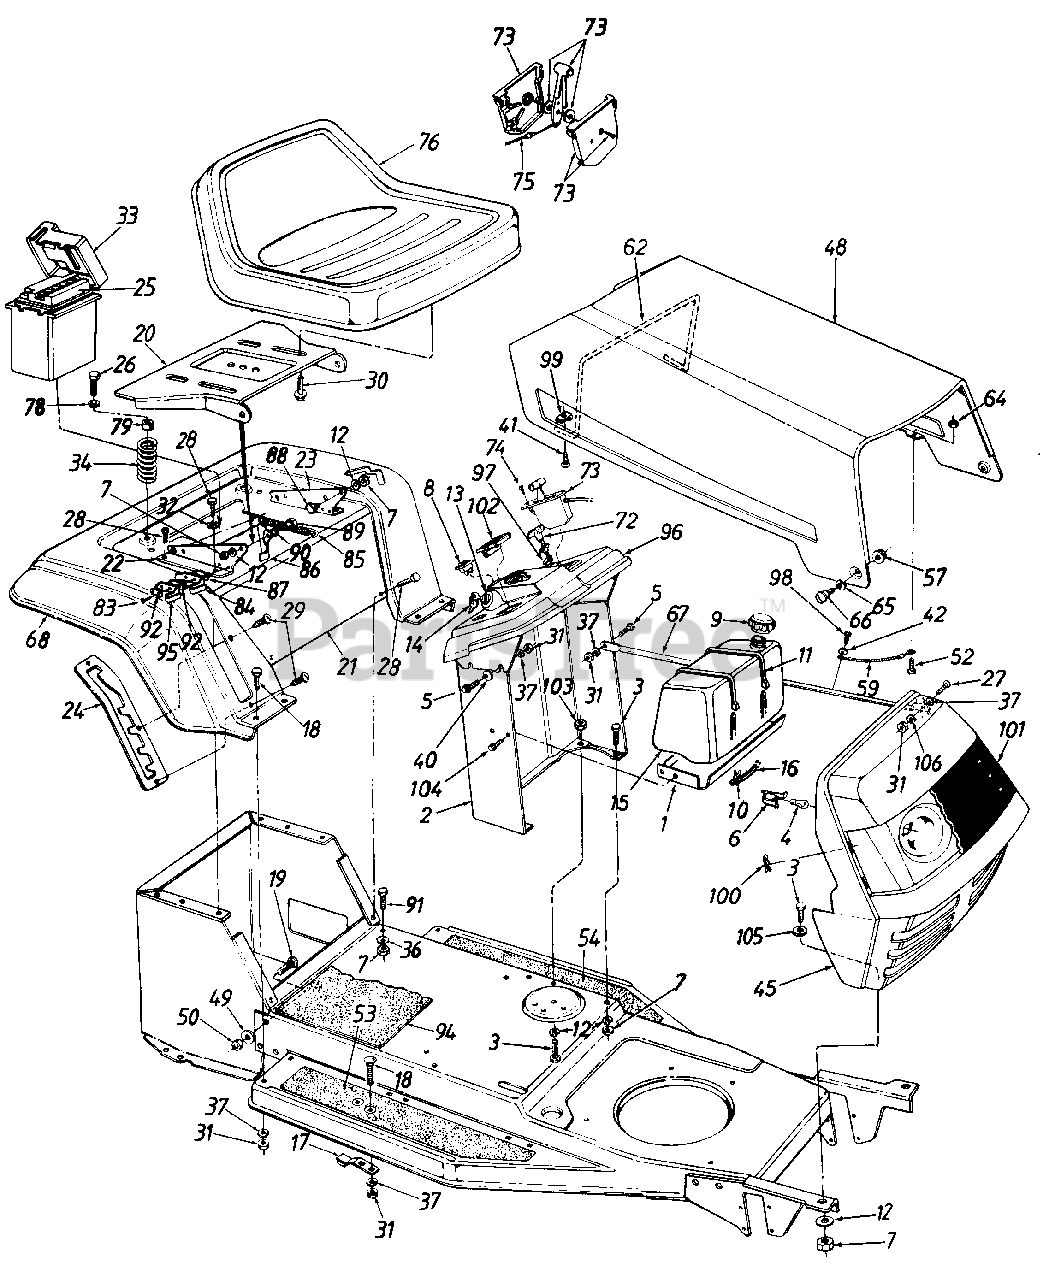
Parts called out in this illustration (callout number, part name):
4	Bulb
5	hex Bolt 1/4 x .62" Lg.
6	Socket
7	Hex Nut 5/16-18 Thd.
8	Light Switch
9	Gas Cap
10	Hose Clamp
11	Cable Tie
12	L-Wash. 5/16" I.D.
13	Ignition Switch
14	Ignition Key
15	Fuel Tank
16	Gas Line 15" Long
17	Blade Brake Ass'y.
18	Carriage Bolt 1/4-20 x .62"
19	Ribbed Neck Bolt 3/8-24 x .8"
25	Battery
26	Hex Self-Tap Screw 5/16-18 x 1.25" Lg.
27	Truss Mach. Scr. 1/4-20 x .75" Lg.
28	Hex AB-Tap Scr. 5/16 x .75" Lg.
29	Torx Mach. AB-Tap Scr. 1/4 x .62" Lg.
30	Hex Self-Tap Scr. 3/8-16 x .75" Lg.
31	Hex Nut 1/4-20 Thd.
32	External L-Wash. 5/16" I.D.
33	Battery Box w/Cover
34	Compression Spring
36	Bell-Wash. 5/16" I.D.
37	L-Wash. 1/4" I.D.
40	Bell-Wash. .265" I.D. x .75"
41	Pan Hd. Scr. 10-24 x .75" Lg.
42	Fl-Wash. .218" I.D. x .62"
50	Hex L-Nut 3/8-24 Thd.
52	Truss Mach. Scr. #10-24 x .5" Lg.
53	Foot Pad - R.H.
54	Foot Pad - L.H.
57	Lock Nut 1/4-28 Thd.
59	Hood Stop
62	Hood Spring
64	Hex Sems Nut #10-24 Thd.
65	Spr. Wash. .39" I.D. x .62" O.D.
66	Shld. Bolt
72	Choke Control
73	Throttle Control Box
74	Truss AB-Tap Scr. #10 x .5"
75	Throttle Wire (B&S)
76	Seat Assembly (Low Back)
78	Fl-Wash. .344" I.D. x .88" O.D.
79	Bushing
83	Hex Tap Scr. #8 x .5" Lg.
84	Safety Switch (Seat)
85	Ext. Spring 5.31" Lg.
86	Seat Lift Brkt.
87	Insulator Boss Plate
88	Shld. Bolt .437" Dia. x .162" Lg.
89	Shld. Bolt .437" Dia. x .268" Lg.
90	Spr. Wash. .445" I.d. x .75" O.D.
91	Hex Wash. Hd. Scr. 5/16-18 x .62" Lg.
92	Insulator Plate
94	Center Foot Pad
95	Safety Switch (Seat)
96	Dash Panel
97	Retainer Clip
98	Truss Mach. B-Tap Scr. #10 x .5" Lg.
99	Speed Nut
100	Internal Cotter Pin 5/16" Dia.
101	Lens
102	Ammeter
103	Hex Jam Nut 5/16-18 Thd.
104	Hex Wash. Hd. Tap Scr. 1/4-20 x .5" Lg.
105	Fl-Wash. .344" I.D. x 1" O.D.
106	Ext. L-Wash. 1/4" I.D.
